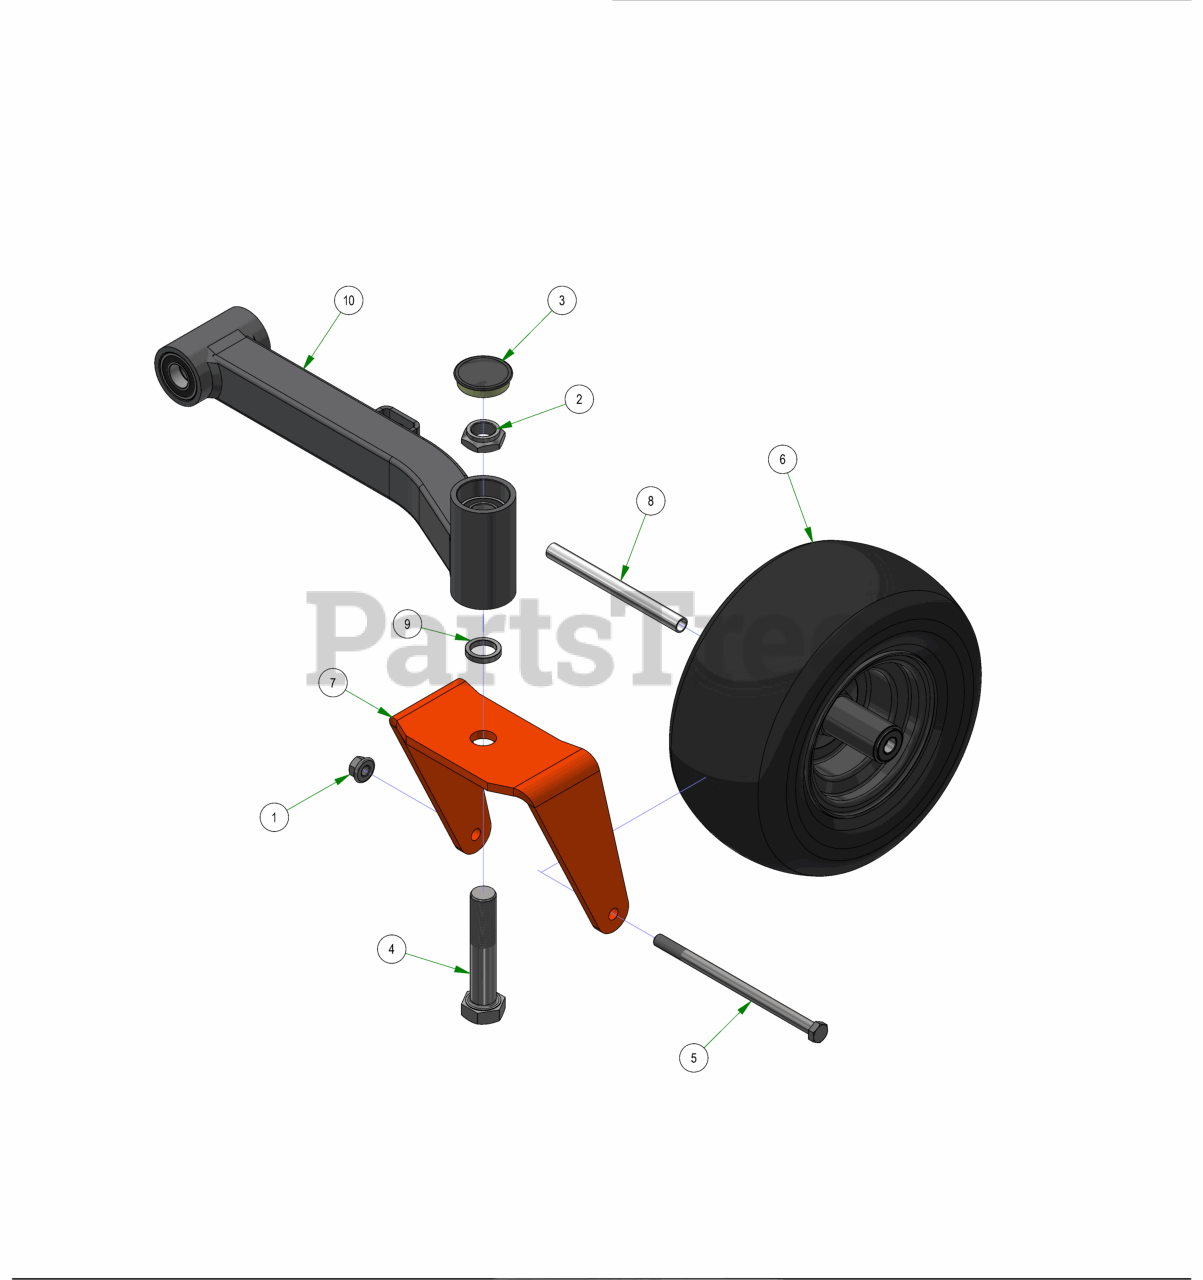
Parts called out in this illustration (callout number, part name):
1	1/2-13 NYLON INSERT FLANGE LOCKNUT ZINC
2	1"-14 NYLON INSERT JAM LOCKNUT ZINC
3	2017 Bearing Cover
4	1"-14 X 5 HEX CAP SCREW (GR.8) ZINC YELLOW
5	1/2-13 X 8-1/2 HEX CAP SCREW (GR.5) ZINC
6	13x6.5-6 Black Tire and Wheel Assembly
7	2017 ZT Front Fork
8	Front Wheel Spanner
9	1.02 ID X 1.38 OD X .250 THK SPACER ZINC
10	2021 ZT Suspension Arm Assembly Left (48", 54", & 60")
